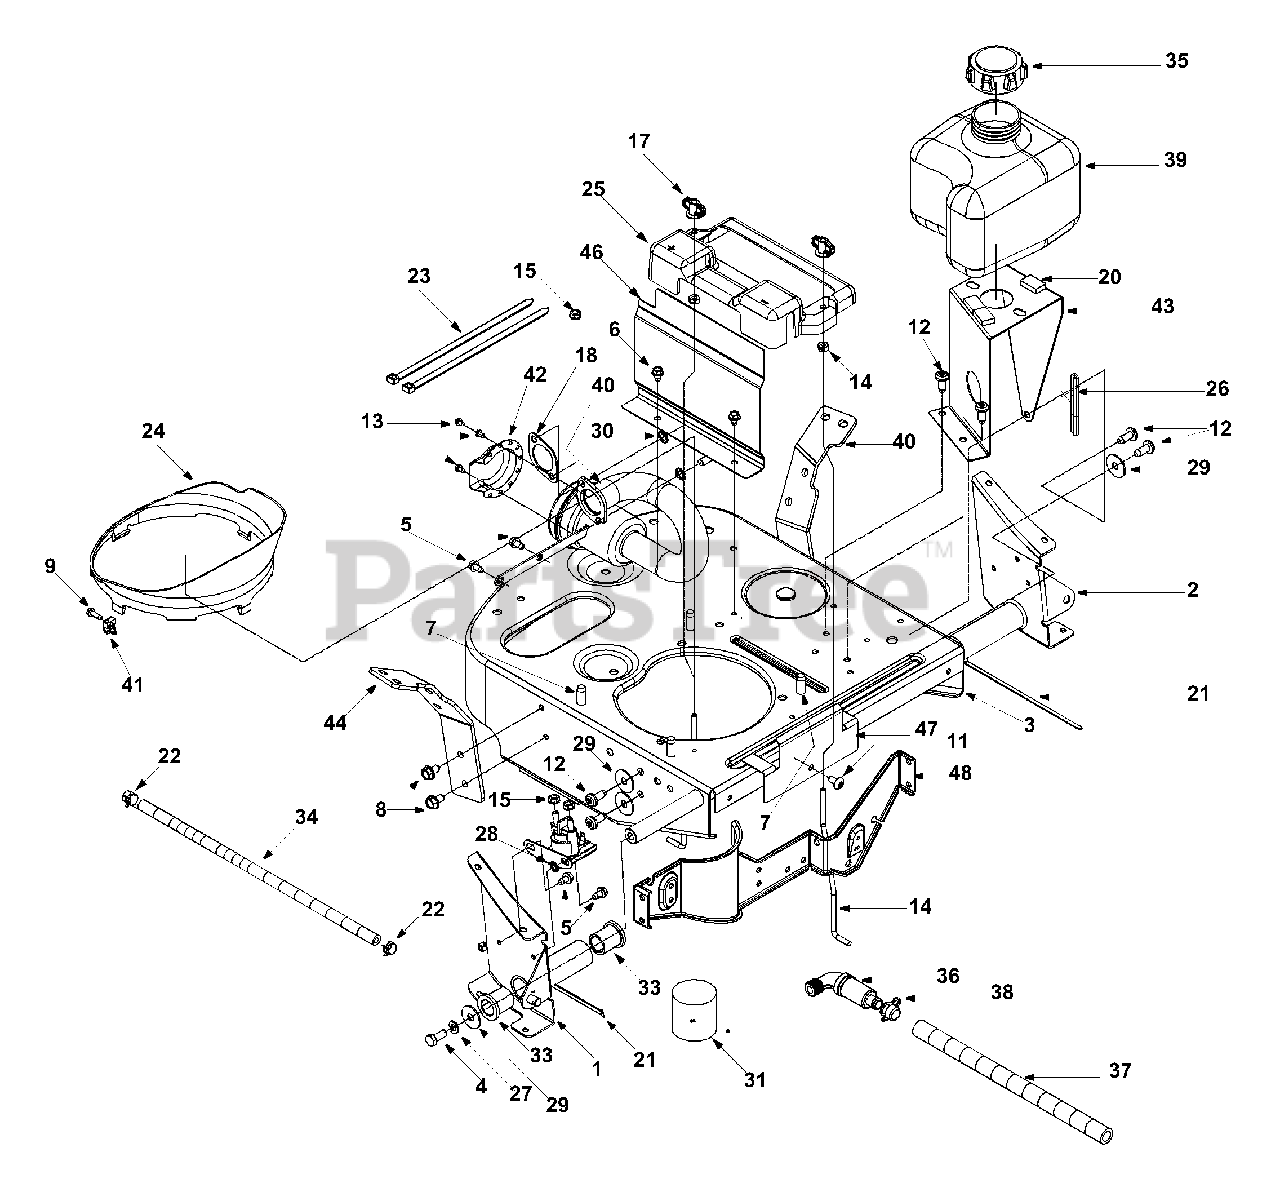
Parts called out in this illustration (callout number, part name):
5	TT Screw 1/4-20 x 0.5"
6	TT Screw 1/4-20 x 0.375"
7	TT Sems Screw 3/8-16 x 1.0"
8	AB Screw 5/16-12 x 0.75"
9	T Screw #10-32 x 0.625"
10	Soc. Hd. Screw 5/16-18 x 0.75"
11	AB Screw 1/4-14 x 0.5"
12	TT Screw 5/16-18 x 0.75"
13	AB Screw 8-18 x 0.375"
14	Battery Hold -Down Rod
15	Sems Nut
16	Hex Lock Nut 1/4-20
17	Wing Nut
18	Exhaust Gasket
19	Pipe Sealant
20	Foam Tape: 0.625 x 0.25 thk.
21	Cable Tie
22	Hose Clamp
23	Cable Tie
24	Plen
25	Battery Cover
26	Trim Strip
27	Lock Washer 5/16
28	External Lock Washer
29	Flat Washer
30	Lock Washer 1/4
31	SAE 30W Oil
32	Elbow Fitting
33	Flange Bearing
34	Fuel Line Hose
35	Fuel Cap
36	Oil Drain
37	Oil Drain Hose
38	Oil Drain Cap
39	Fuel Tank
40	Muffler
41	Clamp Casing: Throttle
42	Muffler Deflector
47	Heat Shield
48	Bracket: Hose Clamp
